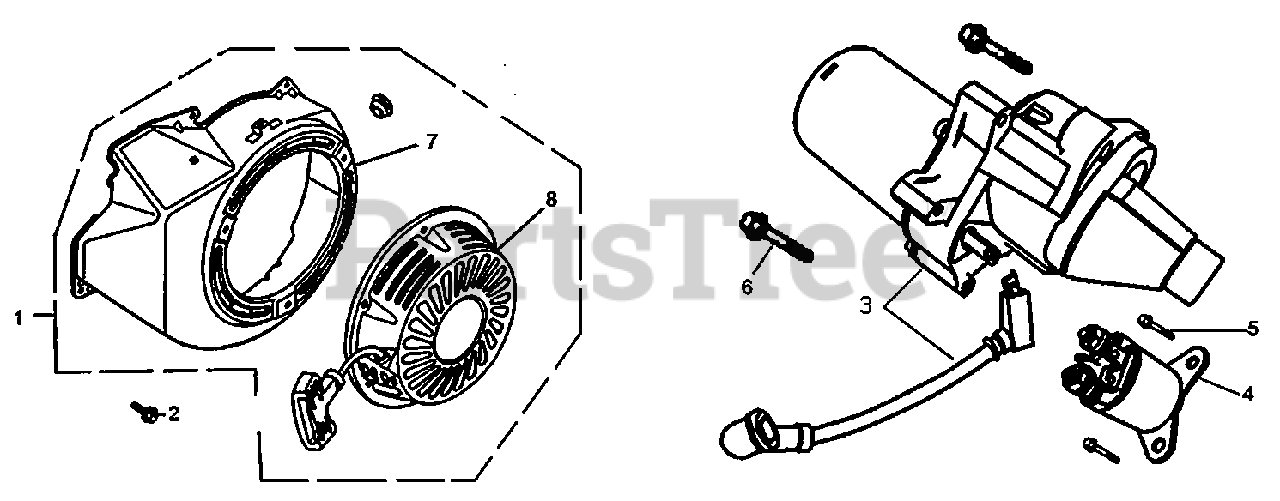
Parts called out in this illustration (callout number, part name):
1	STARTER ASSY.
2	BOLT, FLANGE
3	STARTER MOTOR
4	CONTACTOR ASSY.
5	BOLT-WASHER
6	BOLT, FLANGE
7	BLOWER HOUSING, RECOIL STARTER
8	ASSY, RECOIL STARTER
